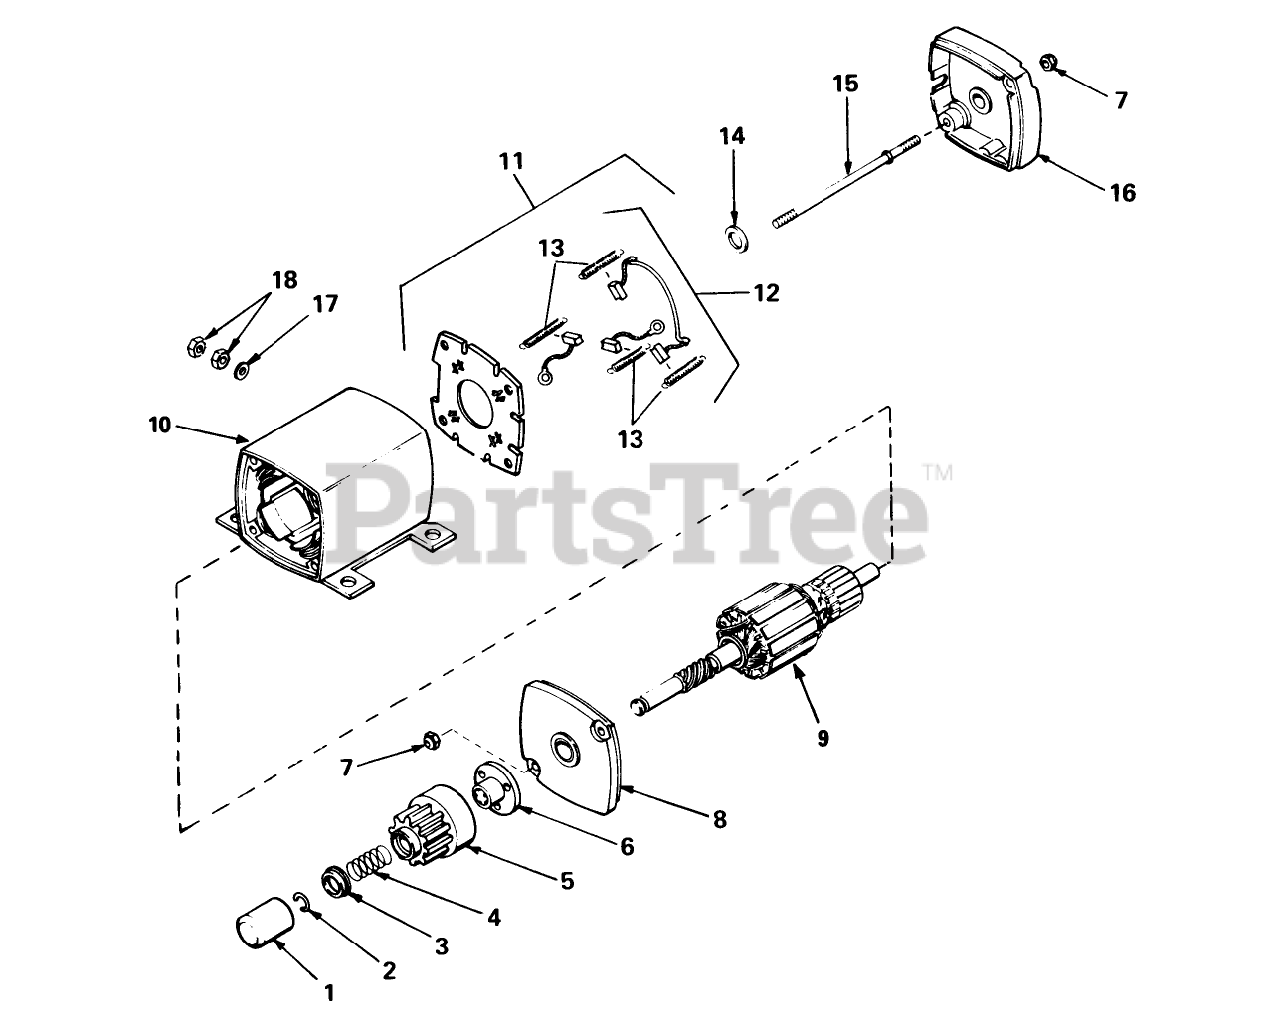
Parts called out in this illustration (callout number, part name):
1	Cover-Dust
2	Ring-Retainer
3	Retainer-Spring
4	Spring-Anti Drift
5	Gear
6	Nut-Engaging
7	Nut-Lock
8	Cap Assy., Drive End
9	Armature
10	Housing Assembly (Incl. Ref. #11)
11	Card Assy., Brush (Incl. No. 12)
12	Brush Spring Kit (Incl. 4 pcs. of #13)
13	1545D SUP TO W/3256
14	Washer-Thrust
15	Bolt
16	2035A67 WIZARD W/34
17	Washer
18	Nut-Hex
